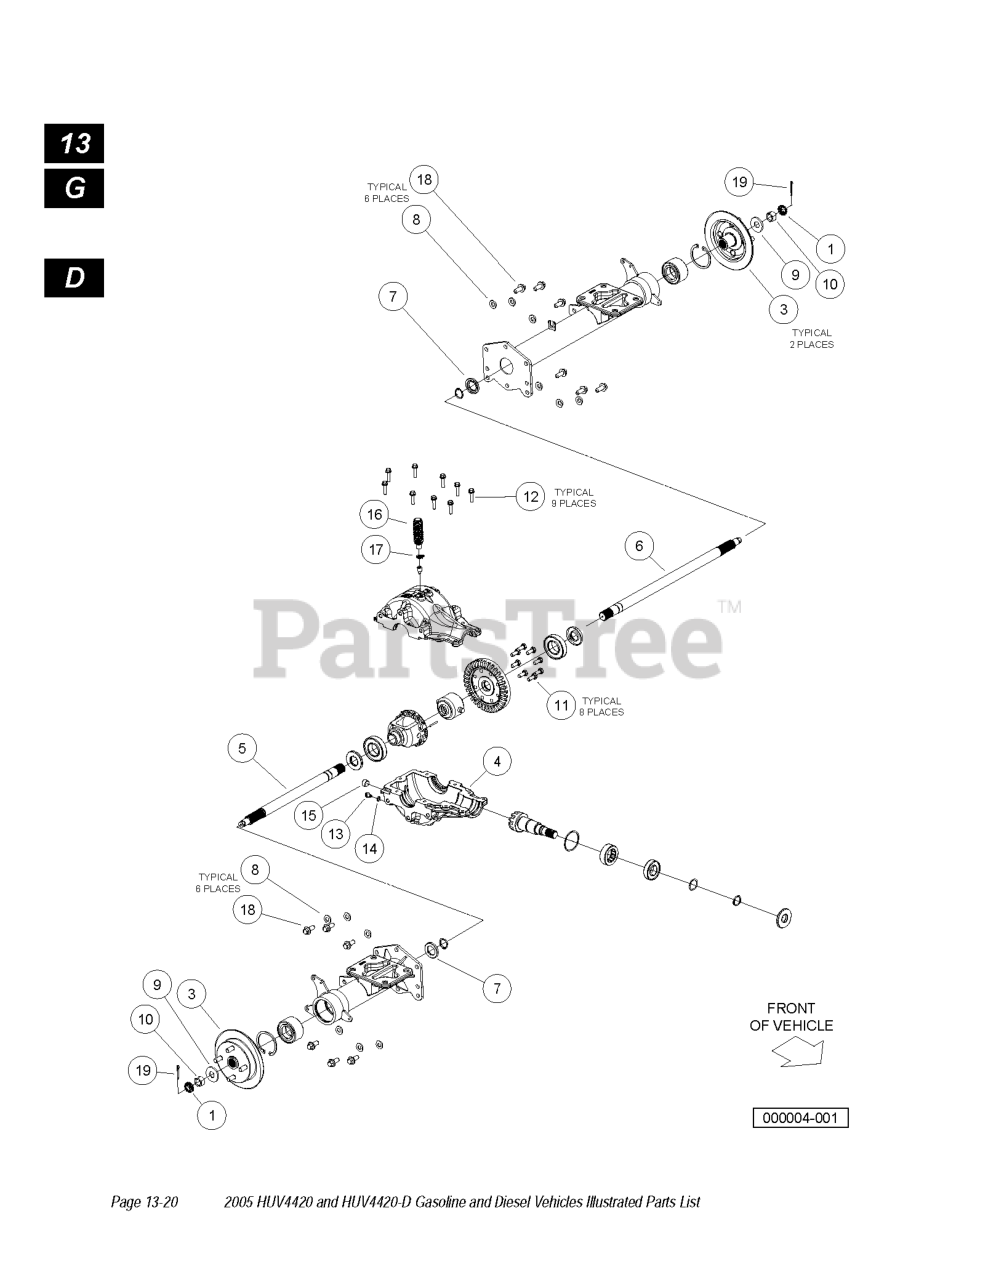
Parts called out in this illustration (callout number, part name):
1	AXLE, REAR
2	LOCKING CAP, NUT
3	ASSY, ROTOR, BRAKE, REAR
4	GEARCASE, LOWER, MACHINED
5	AXLE, RH
6	AXLE, LH
7	WASHER, COUNTERBORED 51 X 30
8	WASHER, BELLEVLE, 1.063 X .043
9	WASHER, BELLEVILLE, 49 X 4
10	NUT, HEX, M20 X 1.5, MODIFIED
11	SCREW, M10 X 25
12	SCREW, HEX FLANGE, M8 X 35
13	PLUG,3/8-16, HEX FLANGE
14	WASHER, .625 X .382 X .60
15	PLUG, SQUARE SKIT, 1/12-14,PTF
16	BELLOWS, VENT, UPPER HOUSING
17	CLAMP, HOSE, DW-9.5
18	SCREW, HEX FL, M12 X 1.75 X 30
19	PIN, COTTER, 5/32 X 1.25
